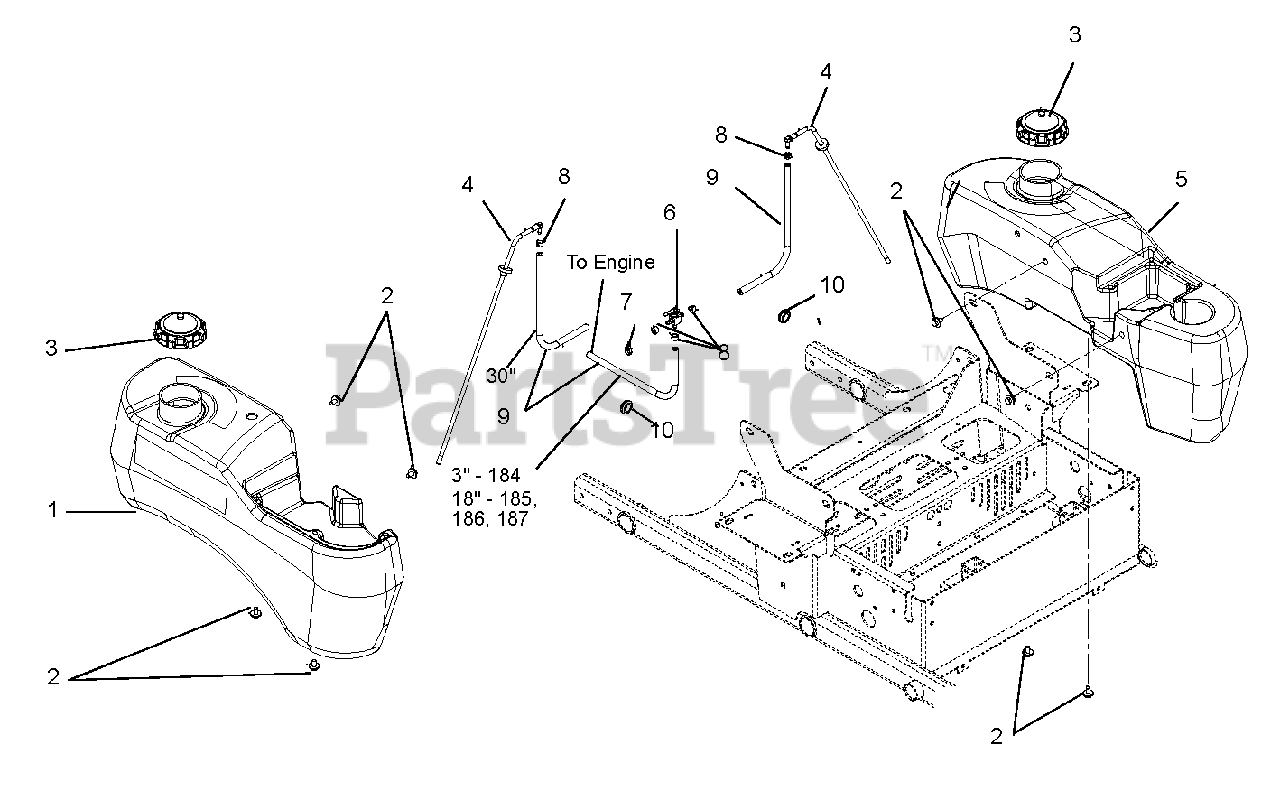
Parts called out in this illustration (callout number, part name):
1	Tank, Right Hand Fuel
2	Bolt, SEMS .31-18 x .62
3	Cap, Fuel
4	Assembly, Large Tank Fuel Pick-up
5	Tank, Left Hand Fuel
6	Valve, Fuel
7	Routing Clip (1/2" ID)
8	Clamp, Fuel Line
9	Hose, .25 Low-PERM Bulk Gas
10	Grommet, Rubber 5/8 ID/1.13 OD
